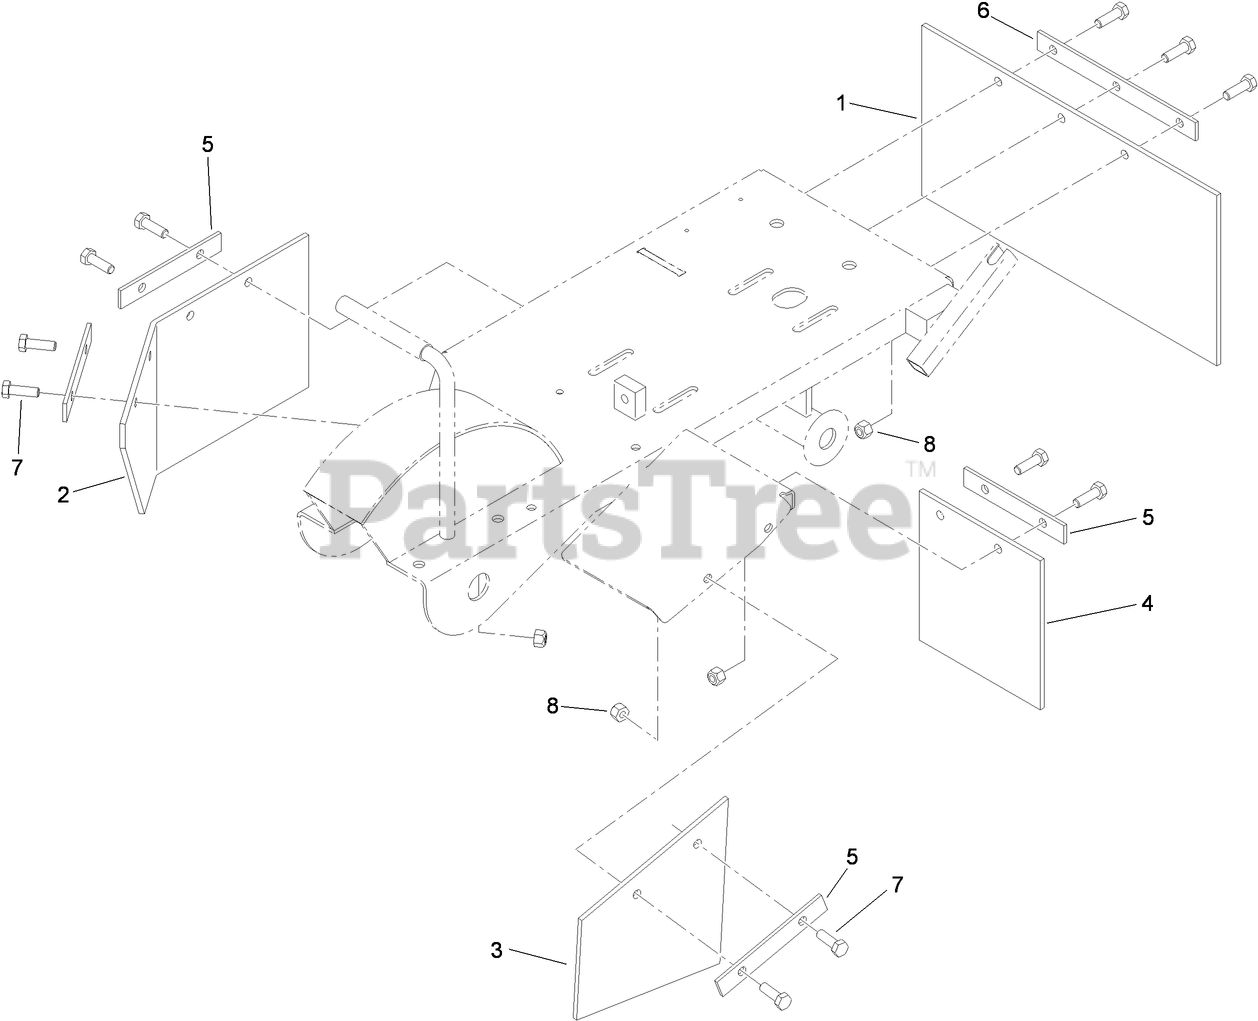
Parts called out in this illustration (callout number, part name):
1	FLAP-REAR
2	FLAP-RIGHT
3	FLAP-WING
4	FLAP-WING, REAR
5	PLATE-MOUNTING, FLAP
6	PLATE-MOUNTING, FLAP (REAR)
7	SCREW-HH
8	NUT-LOCK, NI
